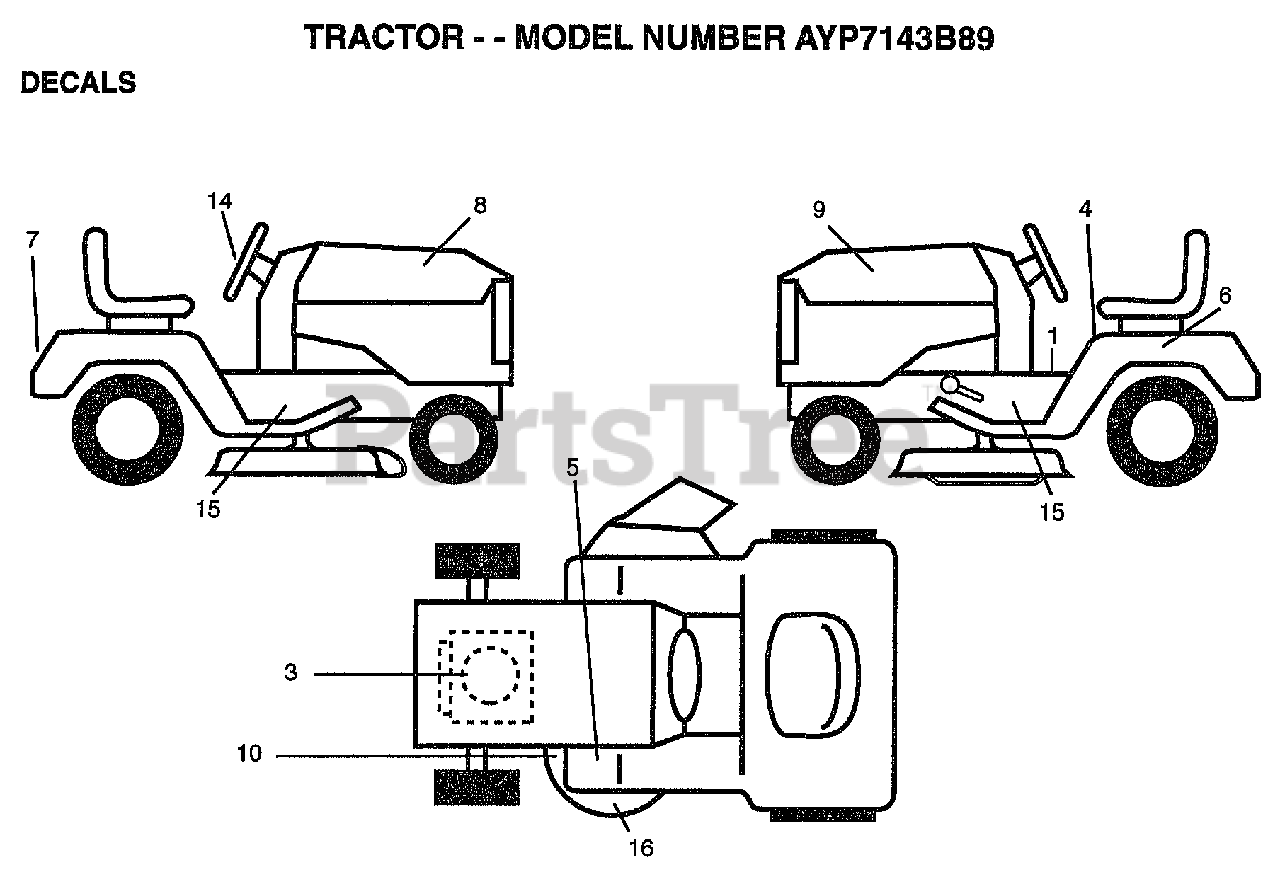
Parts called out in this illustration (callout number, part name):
1	"DECAL DASH,OPER."
3	DECAL, ENGINE
4	"DECAL DANGER,FEND"
6	DECAL.BATRY.3-3908
8	DECAL.HOOD.RH
9	DECAL.HOOD.LH
10	"DECAL-SCHEM,BELT"
14	DECAL.INS.STRG.WL
15	DECAL CHASSIS WIZ
16	DECAL DECK WIZ +
